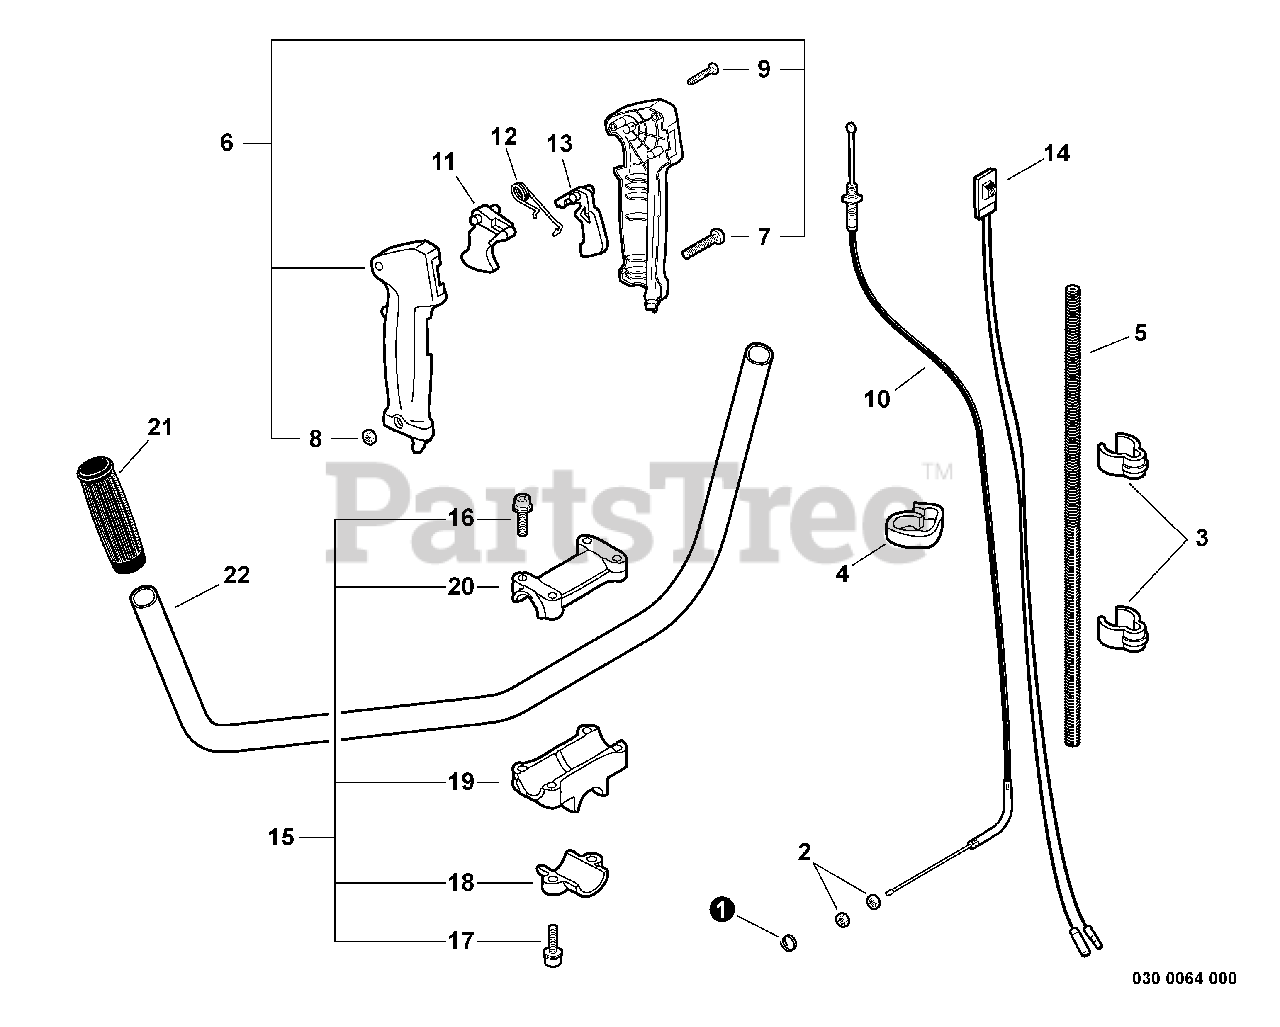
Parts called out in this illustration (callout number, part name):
5	TUBE, PROTECTIVE - CORRUGATED
6	THROTTLE CONTROL ASSY
7	SCREW - 5X30
9	SCREW - 3X25
10	CABLE, THROTTLE
11	TRIGGER, THROTTLE
12	SPRING, LOCKOUT LEVER
13	LOCKOUT, THROTTLE
14	SWITCH, IGNITION
15	HANDLE BRACKET KIT
16	SCREW - 5X25
17	SCREW - 5X25
18	BRACKET, MOUNTING
19	BRACKET, HANDLE - LOWER
20	BRACKET, HANDLE - UPPER
21	GRIP, HANDLE - LEFT
22	HANDLE - FRONT
